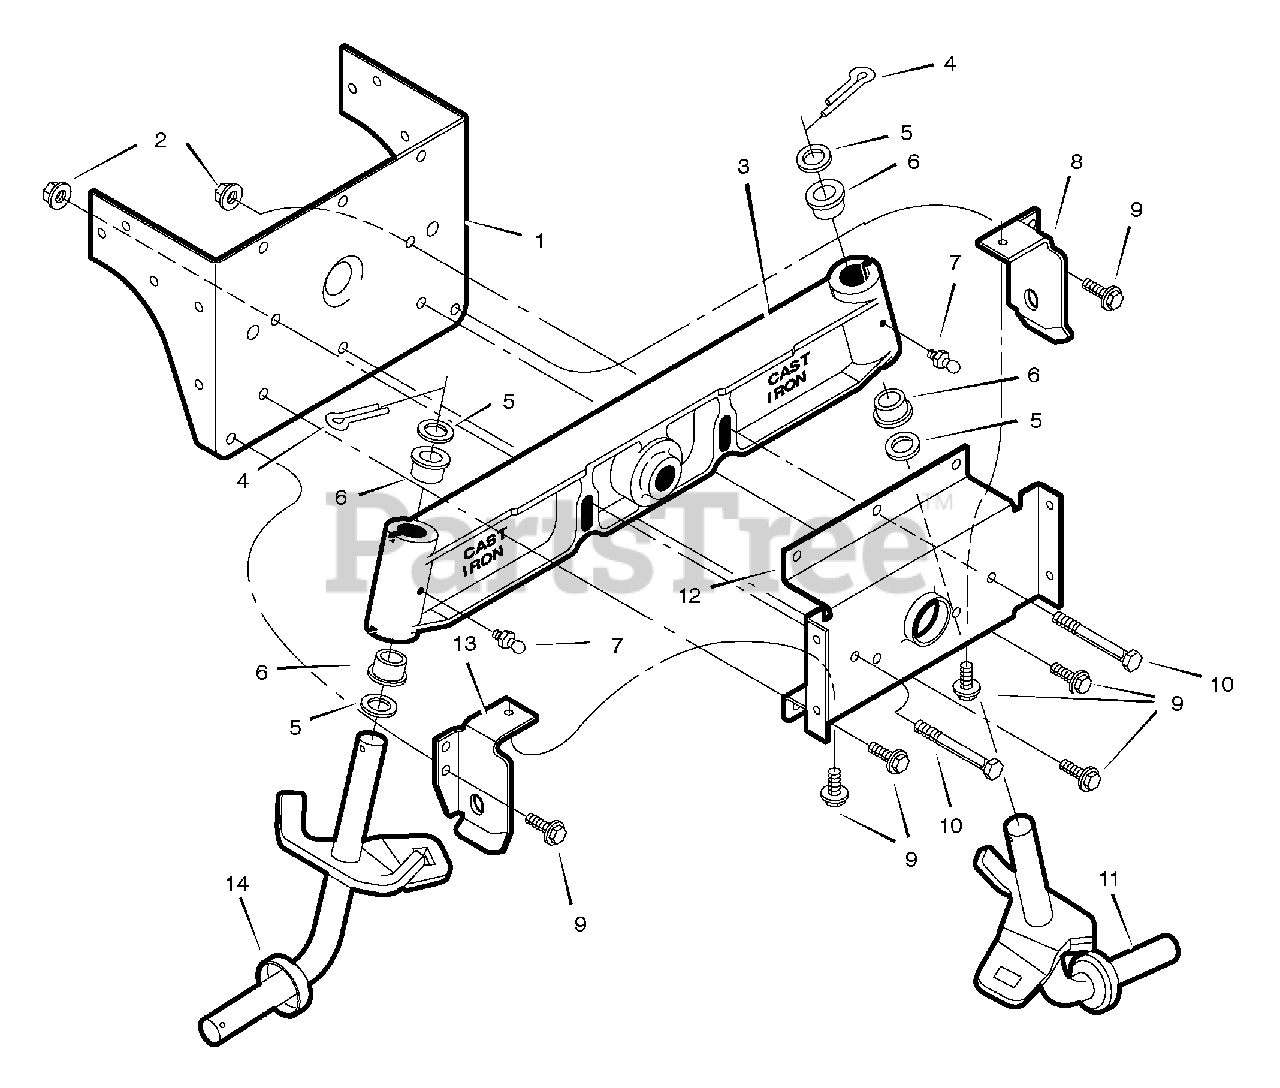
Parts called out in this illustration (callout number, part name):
1	Bracket, Rear Hanger
2	Nut, Flange
3	Axle Assembly
4	Pin, Hair
6	Bearing, Spindle
7	Fitting, Lub
8	Hanger, Left Deck
11	Spindle Assembly, Left
12	Hanger, Axle
13	Hanger, Right Deck
14	Spindle Assembly, Right
